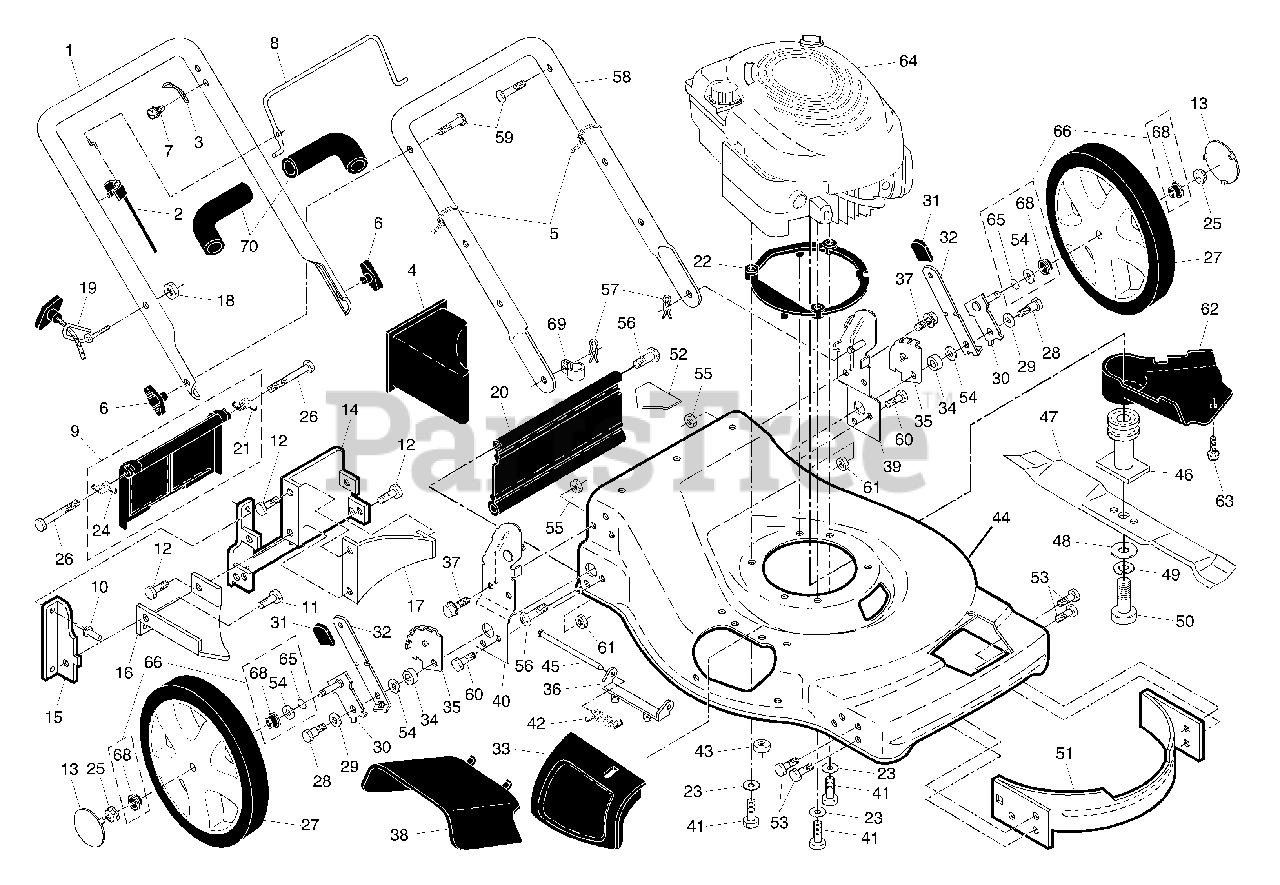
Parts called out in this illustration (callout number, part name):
1	Upper Handle
2	Engine Zone Control Cable
3	Bracket, Upstop
4	Mulcher Plug
5	Wire Tie
6	Handle Knob
8	Control Bar
9	Rear Door Assembly
11	Screw, Self-Tapping #10-24 x 5/8
12	Screw, Hex Hex Head, Sems 1/4-20 x 1/2
13	Hubcap
14	Back Plate
15	Side Baffle
16	Discharge Baffle
17	Rear Baffle
18	Keps Locknut 1/4-20
19	Rope Guide
20	Rear Skirt
21	Spring, Rear Door, LH
22	Spacer, Engine
23	Washer, Flat
24	Spring, Rear Door, RH
25	Nut, Hex, Flanged
26	Bolt, Rear Door
27	Wheel, Rear
28	Bolt, Shoulder 3/8-16 x 1
29	Washer, Belleville
30	Axle Arm Assembly
31	Selector Knob
32	Selector Spring
33	Mulcher Door
34	Spacer
35	Wheel Adjusting Bracket
36	Hinge Bracket Assembly
37	Screw, Sems, Thread Cutting 5/16-18 x 3/4
38	Discharge Deflector
39	Handle Bracket Assembly, LH
40	Handle Bracket Assembly, RH
41	Screw, Hex Head, Threaded, Rolled 3/8-16 x 1-1/8
42	Spring, Torsion
43	Nut, Hex, Nylock
44	Kit, Lawn Mower Housing
45	Rod, Hinge
46	Blade Adapter / Pulley
47	Blade, 22"
48	Washer, Hardened
49	Washer, Helical
50	Screw, Machine, Hex Head 3/8-24 x 1-3/8 Grade 8
51	Front Baffle
52	Danger Decal
55	Locknut, Hex 3/8-16
56	Screw, Hinge 1/4-20 x 1-1/4
57	Hairpin Cotter
58	Lower Handle
59	Handle Bolt
61	Nut
62	Debris Shield
63	Screw, Debris Shield
65	O-Ring
66	Kit, Bushing, High Wheel
68	Bushing, Nylon, Black
69	Clip, Cable
